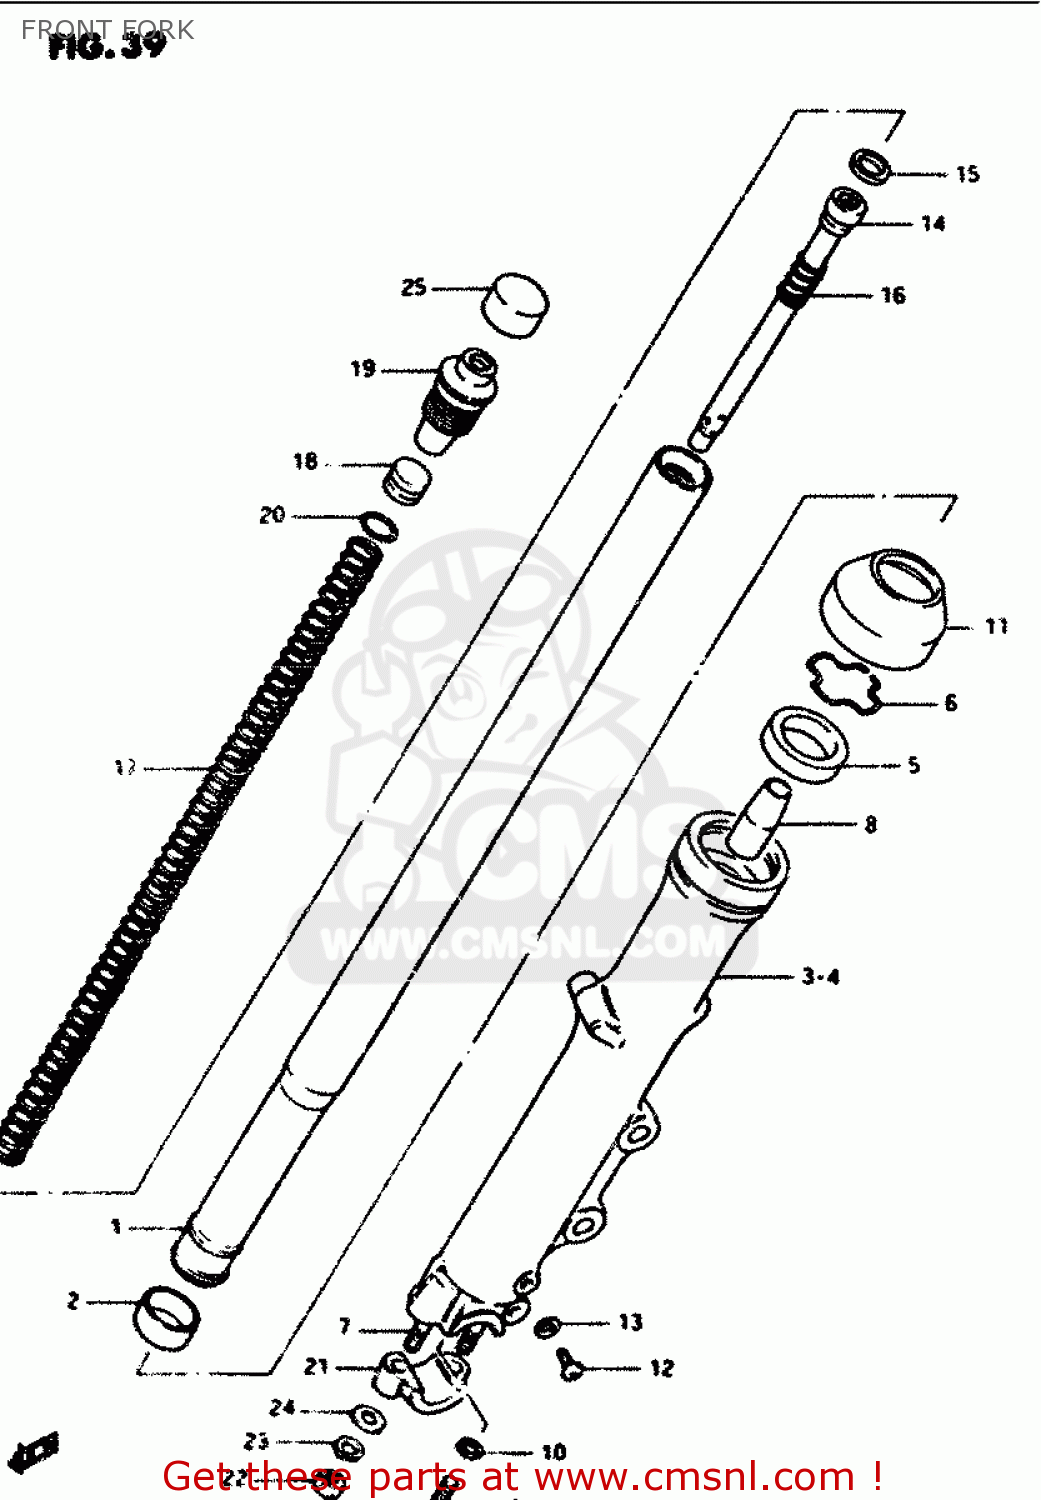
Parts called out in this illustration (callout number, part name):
1	TUBE,FORK,INNER
2	PISTON
3	TUBE,FORK,OUTER,RIGHT
4	TUBE,FORK,LEFT,OUTER
5	OIL SEAL,FRONT FORK
6	RING,STOPPER
7	BOLT,STUD
8	PIECE,OIL LOCK
9	BOLT,FORK CYLINDER(10X25)
10	GASKET (NAS)
11	SEAL,DUST
12	SCREW
13	GASKET,DRAIN,PLUG (NAS)
14	CYLINDER,FRONT FORK
15	RING,PISTON
16	SPRING,REBOUND
17	SPRING,FRONT FORK
18	PISTON,FREE
19	CAP
20	O-RING
21	HOLDER,AXLE
22	NUT (8MM)
23	LOCK WASHER
24	WASHER
25	CAP,RUBBER
